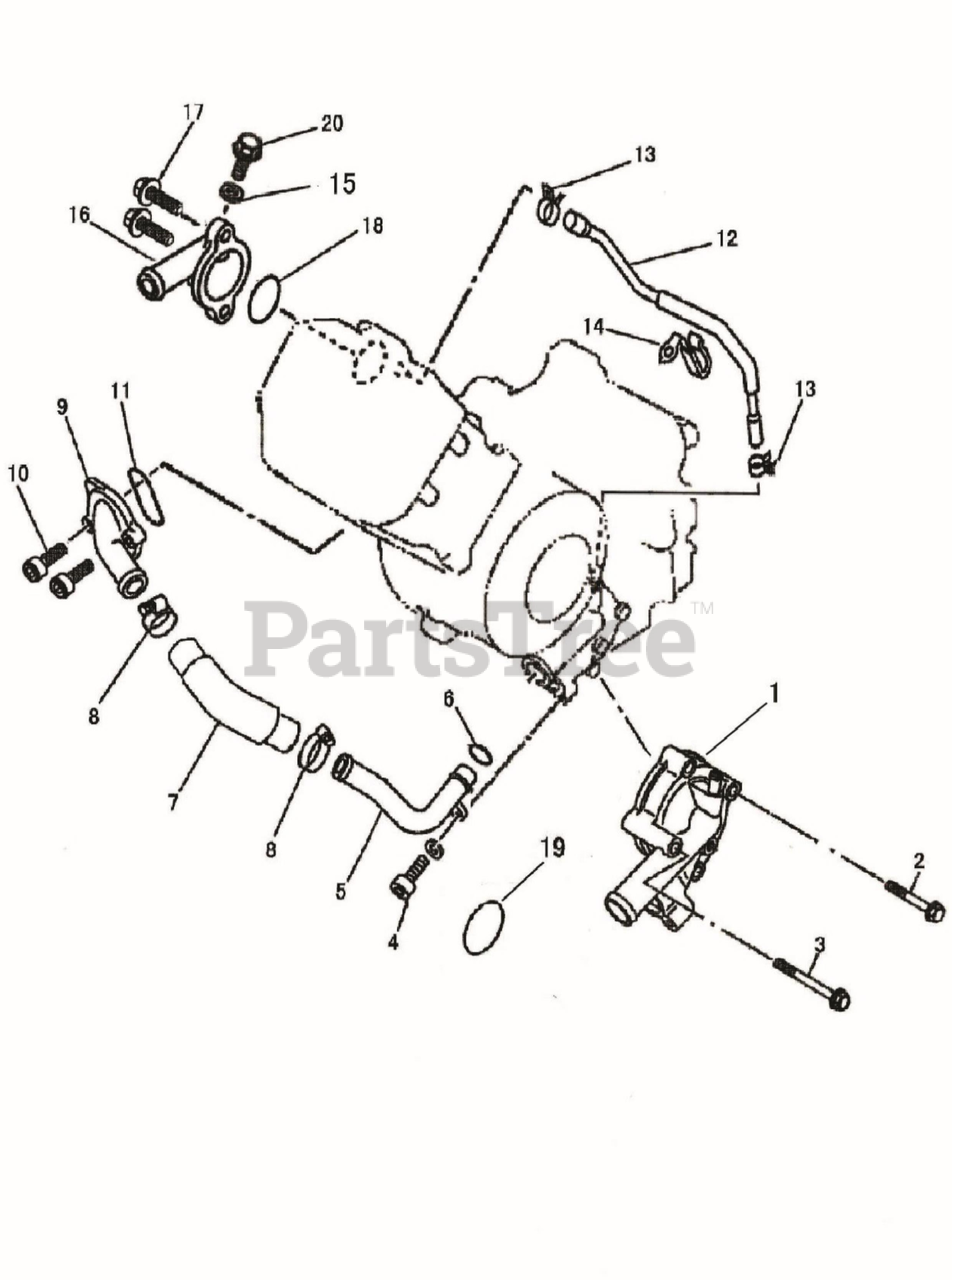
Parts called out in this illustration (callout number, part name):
1	Water Pump Assy
2	Hex flange bolts M6x45
3	Hex flange bolts M6x65
4	Hex flange bolts M6x16
5	Water pipe II
6	O-Ring 20.7x2.6
7	Hose,Cylinder?Water In
8	Screw Clip D
9	Hose Joint,Cylinder,Water Out
10	Hex flange bolts M6x20
11	O-Ring 33.4x2.4
12	Water pipe I
13	Spring clamp C
14	Pipe Clamp I
15	Aluminum Washer 6x12x1.5
16	Cover,Thermostat
17	Hex flange bolts M6x20
18	Seal,thermostat cover
19	O-Ring 34.2x2.5
20	Hex flange bolts M6x12
